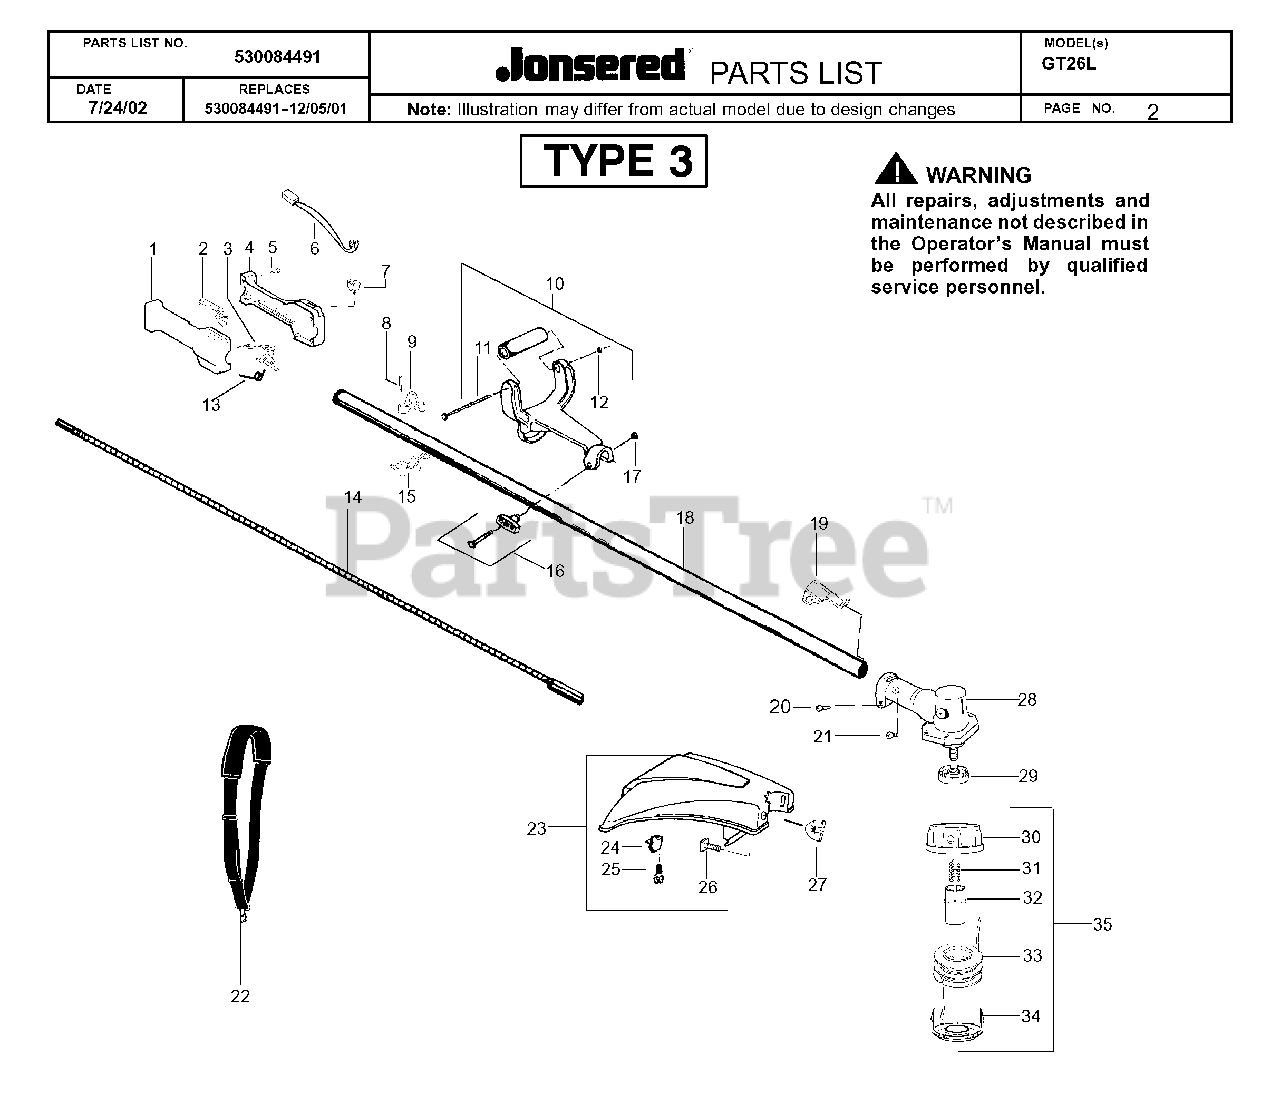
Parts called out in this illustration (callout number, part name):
3	THROTTLE TRIGGER
5	SCREW-10-14 X 13/16 (PL
8	SCREW-10-16 X 1-3/8 PLA
9	CLAMP HARNESS - UPPER
10	ASS'Y-HANDLE ANTIVIB
11	SCREW-12-24 X 4-11/16 P
12	NUT-12-24 (HEX)
16	KIT "T" HANDLE
19	BRACKET,SHIELD
20	SCREW - CARB. ADAPTOR
22	STRAP SHOULDER
23	SHIELD KIT ASS'Y, TYPE 2
24	LINE LIMITER, TYPE 2 NLA
25	SCREW-10-16 X 1/2, TYPE 2
26	BOLT, TYPE 2
27	NUT - HANDLE/SHIELD
28	GEARBOX
33	SPOOL W/LINE
35	CUTTING HEAD
530031159	HEX WRENCH 5/32
